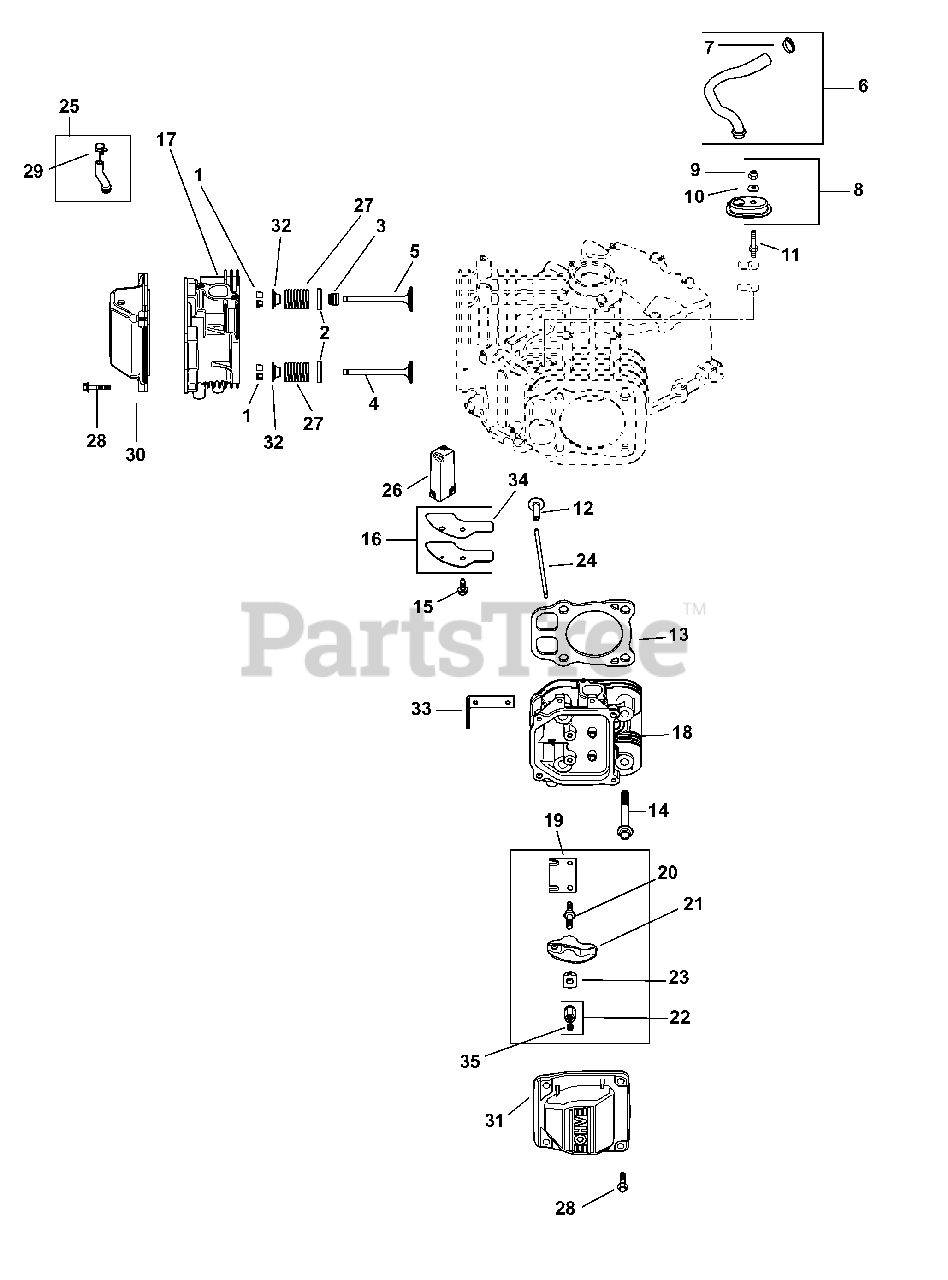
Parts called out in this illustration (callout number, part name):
1	Retainer Kit
2	Spring Retainer
3	Valve Stem Seal
4	Exhaust Valve (STD)
5	Intake Valve (STD)
6	Breather Hose Kit (Inc. #7)
7	Hose Clamp, 1/2
8	Breather Housing Kit (Inc. #9 & 10)
9	Lock Nut, M5 x .8
10	Sealing Washer
11	Breather Cover Stud
13	Cylinder Head Gasket Kit
14	Flange Screw, M10 x 1.5 x 90
15	Flange Screw, M6 x 1.0 x 16
16	Breather Cover Kit
17	#1 Cylinder Head Assembly Kit
18	#2 Cylinder Head Assembly Kit
22	Hex Nut Assembly
23	Rocker Arm Pivot
25	Fuel Pump Hose w/ Clamp Kit
26	Breather Filter
27	Valve Spring
28	Pan Head Screw
30	Rocker Stamped Steel Cover
31	Rocker Stamped Steel Cover
32	Valve Spring Cap
33	Lifting Strap
34	Breather Cover
